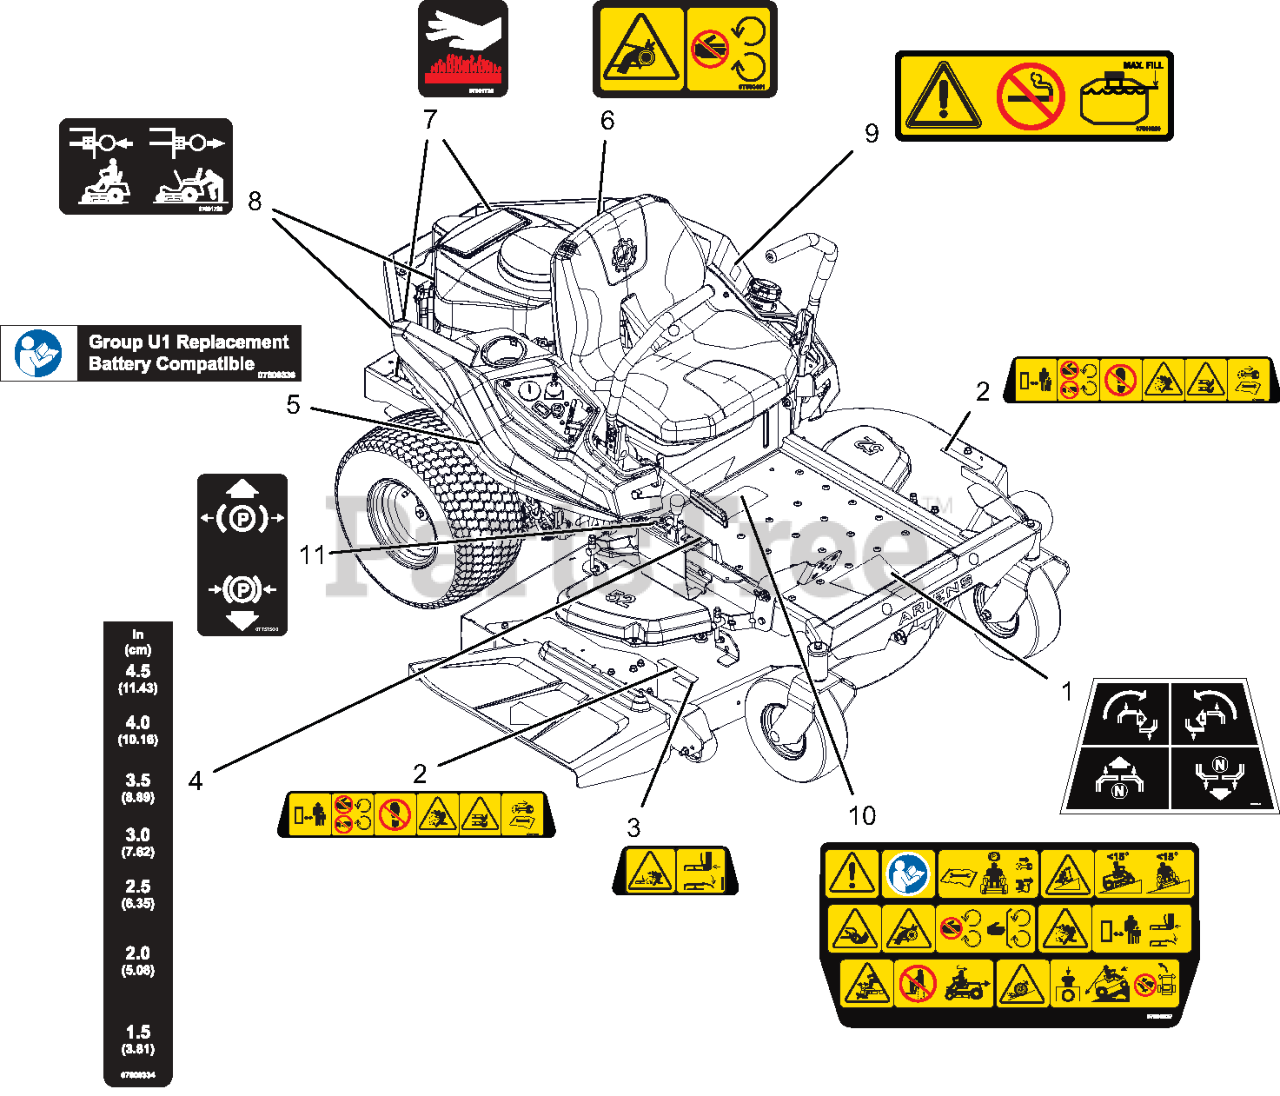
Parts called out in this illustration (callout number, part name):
1	DECAL, STEERING
2	DECAL- SAFETY - MOWER DECK
3	DECAL- SAFETY - DECK GUARDING
4	DECAL, HEIGHT OF CUT
5	DECAL, U1 BATTERY REPLACEMENT
6	DECAL, SAFETY - GUARDING
7	DECAL- HOT SURFACE
8	DECAL- TRANSAXLE DISCONNECT
9	DECAL, FUEL WARNING
10	DECAL, MAIN SAFETY
11	DECAL, PARKING BRAKE LEVER
